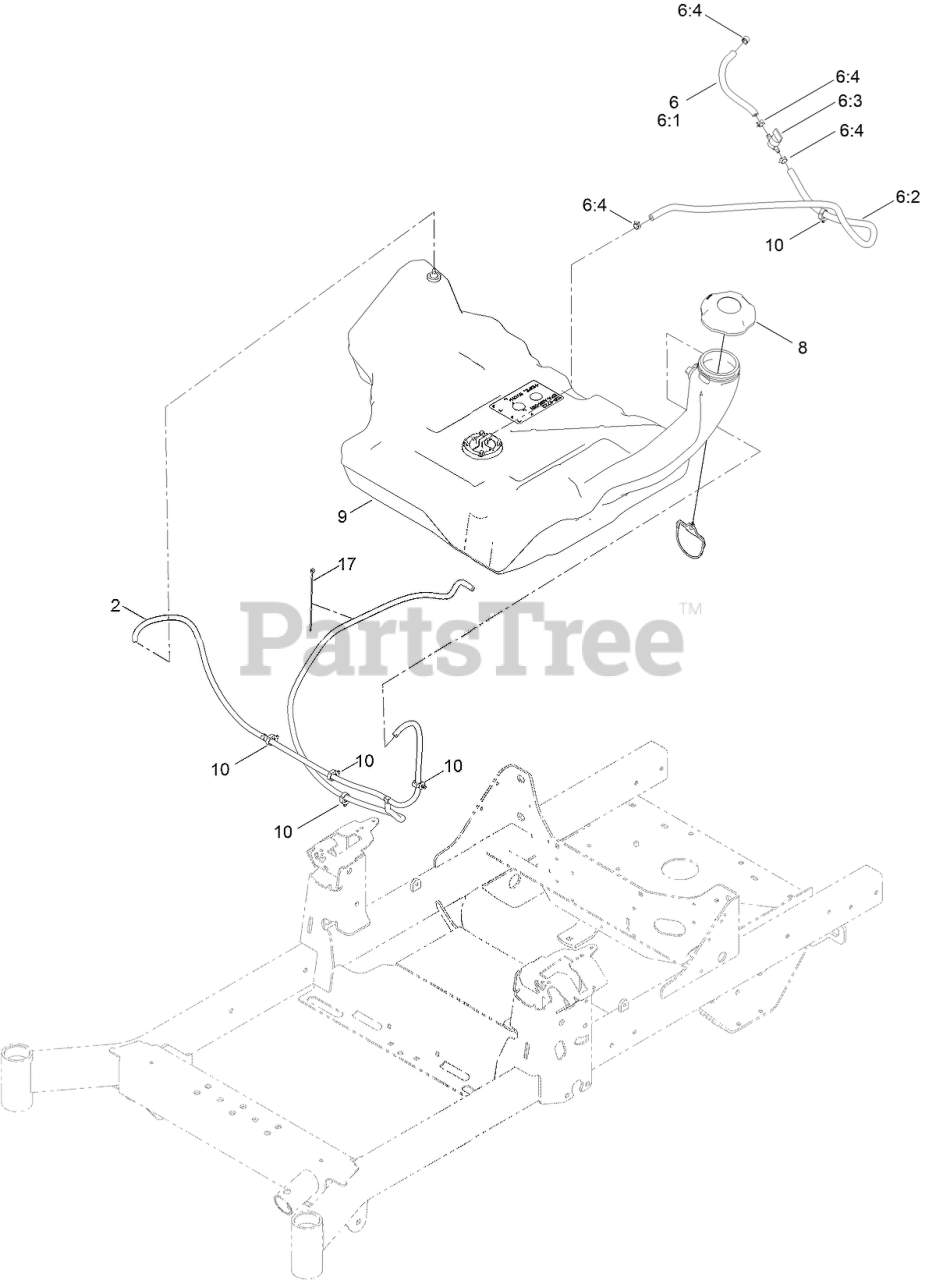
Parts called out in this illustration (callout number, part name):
2	HOSE-VENT
6	FUEL HOSE ASM
6:1	HOSE-FUEL
6:2	HOSE-FUEL
6:3	VALVE-FUEL
6:4	CLAMP-HOSE
8	CAP-FUEL, RATCHETING
9	TANK-FUEL
17	TIE-CABLE
